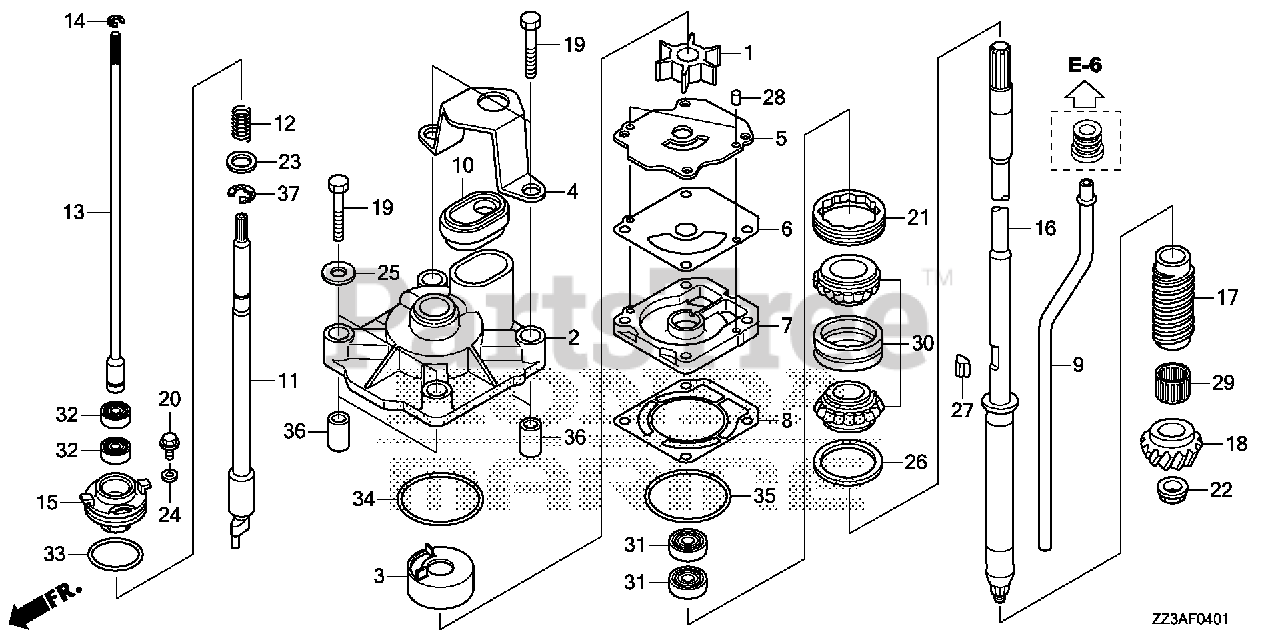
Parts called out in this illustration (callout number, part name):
1	IMPELLER, PUMP
2	HOUSING, IMPELLER
3	LINER, PUMP
4	HOLDER, WATER TUBE SEAL
5	COVER, IMPELLER
6	GASKET B, IMPELLER (POWER THRUST)
7	HOUSING, WATER PUMP
8	GASKET, WATER PUMP
9	TUBE, WATER (XL)(POWER THRUST)
10	RUBBER, WATER TUBE SEAL
11	ROD, SHIFT (L)
12	SPRING, SHIFT ROD
13	ROD A, SHIFT (XL)
14	RING, STOPPER
15	HOLDER, SHIFT ROD
16	SHAFT, VERTICAL (XL)(POWER THRUST)
17	SLINGER, OIL
18	GEAR, PINION (12T)
19	BOLT, HEX. (8X55)
20	BOLT, FLANGE (6X12)
21	NUT, LOCK (64MM)
22	NUT, HEX. (16MM)
23	WASHER, PLAIN (12MM)
24	WASHER, PLAIN (6MM)
25	WASHER (8MM)
26	SHIM A, GEAR (0.10)
26	SHIM B, GEAR (0.15)
26	SHIM C, GEAR (0.30)
26	SHIM D, GEAR (0.50)
27	KEY, WOODRUFF
28	PIN, DOWEL (6X10)
29	BEARING, NEEDLE (1-1/8X1-1/2X1-1/4)
30	BEARING, TAPER ROLLER (30X62X40)
31	SEAL, WATER (23X36X6)
32	SEAL, WATER (12X21X6)
34	O-RING, WATER PUMP
35	O-RING (58.5X3.5)
36	COLLAR, DISTANCE
37	E-RING (10MM)
